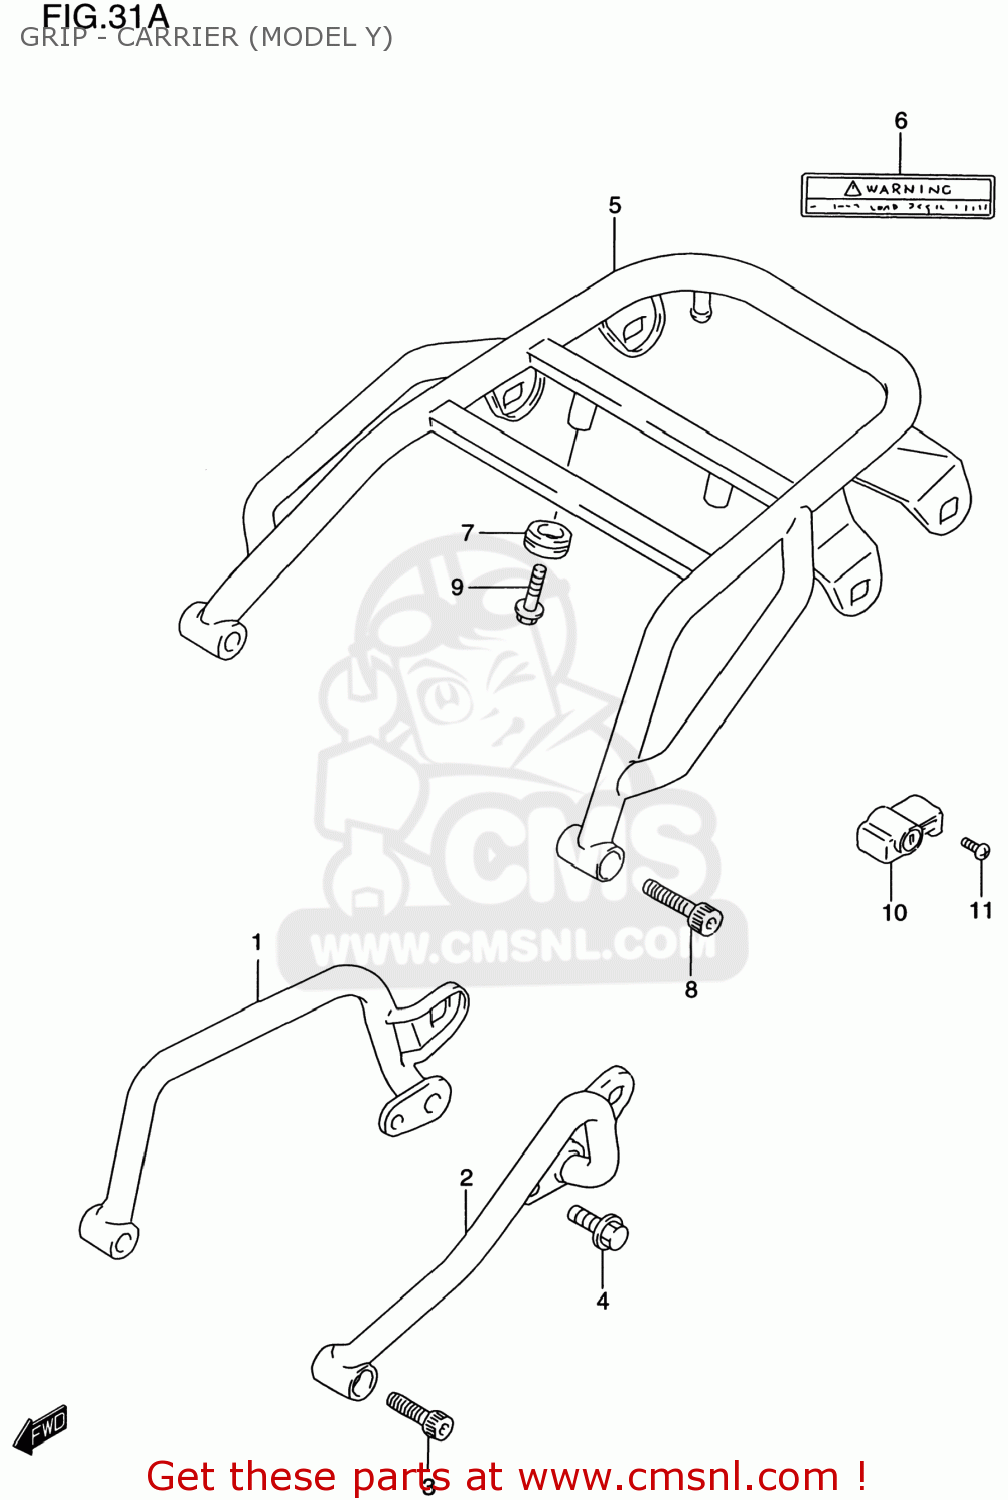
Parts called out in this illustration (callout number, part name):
1	GRIP,RR,R
2	GRIP,RR,L
3	BOLT
4	BOLT
5	REAR RACK SET,FOR E03
6	LABEL,WARNING RR CARRIER
7	GROMMET
8	BOLT
9	BOLT
10	LOCK SET,HELMET
11	SCREW(6X14)
